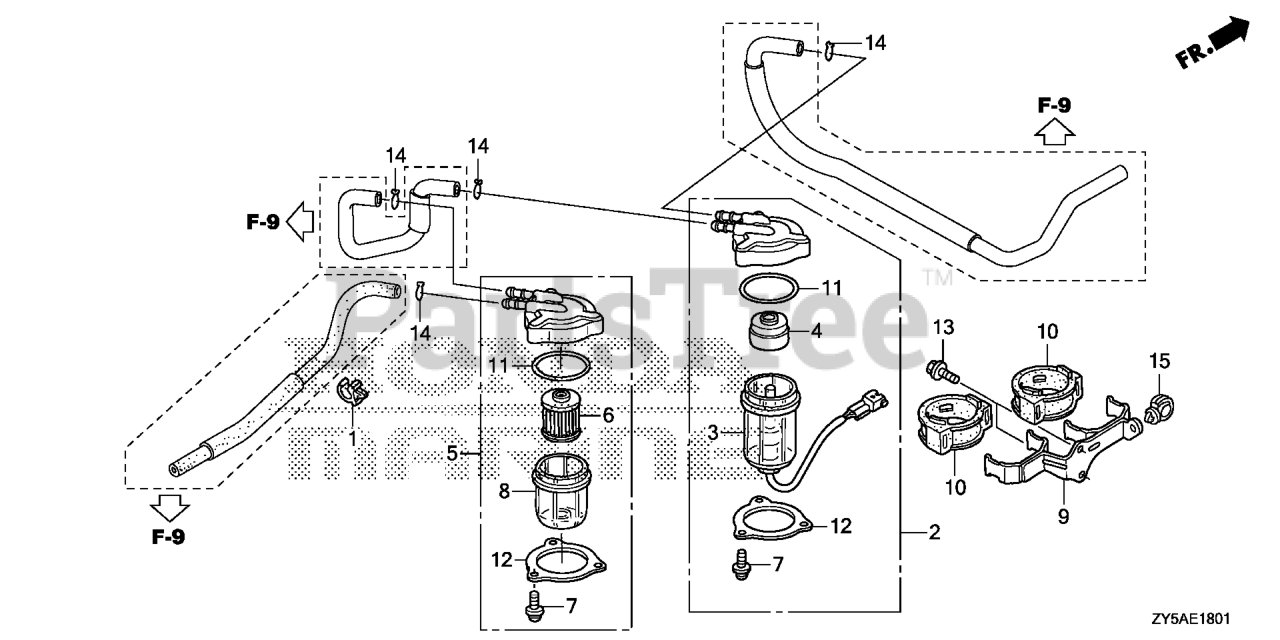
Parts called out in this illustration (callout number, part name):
1	CLIP, TUBE
2	SEPARATOR ASSY., WATER
3	CUP SET, WATER SEPARATOR
4	BUFFER, PLATE
5	FILTER, FUEL
6	FILTER, FUEL
7	SCREW, PAN (5X12)
8	CUP, FUEL STRAINER
9	STAY, FUEL STRAINER
10	SUSPENSION, STRAINER
13	BOLT, FLANGE (6X14)
14	CLIP, TUBE (B12)
15	CLIP, WIRE HARNESS (25MM)
